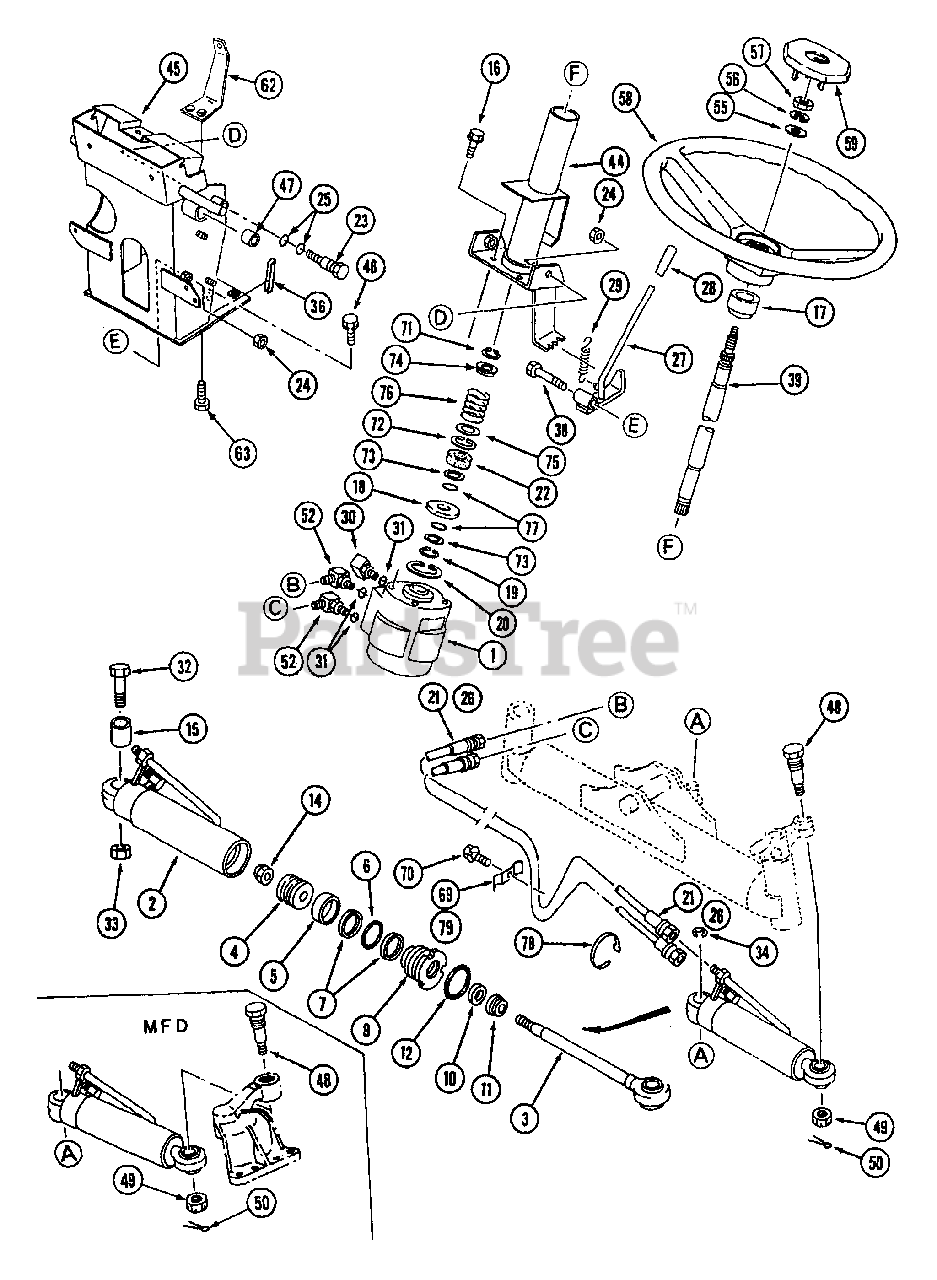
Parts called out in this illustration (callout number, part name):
1	Steering Unit
3	Rod, Cylinder
17	Bushing, Column
26	Hose
39	Shaft, Steering
52	Elbow
58	Steering Wheel
69	Clamp
